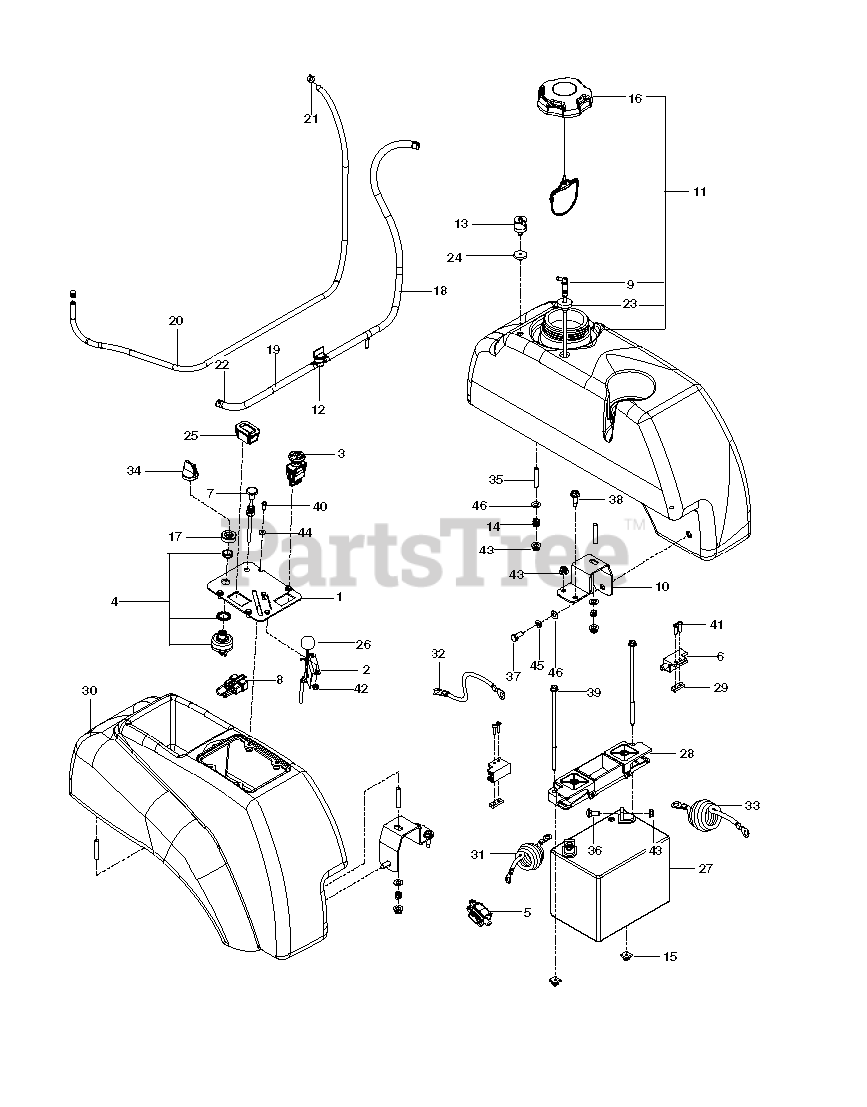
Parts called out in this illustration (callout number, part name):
1	PLATE.CONSOLE.BLACK
2	THROTTLE CONTROL W/BALL KNOB
3	RP SWITCH.PTO.TERMINAL.STD.RED
4	SWITCH, IGNITION, INDAK
5	SWITCH, BRAKE 3P
6	SWITCH INTERLOCKT
7	CABLE, CHOKE
8	PLUG, TIMER
9	FITTING, FUEL
10	SUPPORT, TANK, BLK
11	TANK FUEL LT ASM MZ GRAY
12	FUEL VALVE
13	VALVE.FUEL.CHECK
15	PUSH NUT-NYLON
16	CAP, FUEL
17	CAP IGNITION NUT
18	HOSE, FUEL .25 ID X 26"
19	GAS LINE 10"
20	HOSE, VAPOR 3/16 X 48"
21	CLAMP, HOSE
22	HOSE CLAMP
23	RUBBER GROMMET
24	GROMMET, CHECK VALVE
25	RP.GUAGE.SRVCMNDR.HRMTR.
26	KNOB.ROUND.BALL.BLACK
27	BATTERY, 12 V 330 AMP
28	BATTERY HOLD DOWN
29	TAPPED PLATE
30	FENDER CONSOLE
31	POST.CABLE LONG
32	CABLE POSITIVE
33	NEG. CABLE, 28"
34	KEY, IGNITION
35	STUD, 5/16C
36	BOLT 5/16C X 3/4" CARRIAGE
37	HCS 5/16C X 3/4
38	RP BLT 5/16-18 X 1 THRD FORM D
39	BOLT - 1/4-20 X 7.5
40	HCS #10-24 X 1/2
41	SCR #10-24 X .75 SKT HD BLK
42	NUT 10-24 NYLOC
43	5/16-18 NYLOC FLANGE NUT
44	WASHER #10
45	WASHER.LOCK.HVY.HLCL.SPR.5/16
46	FLAT WASHER 5/16 SAE
